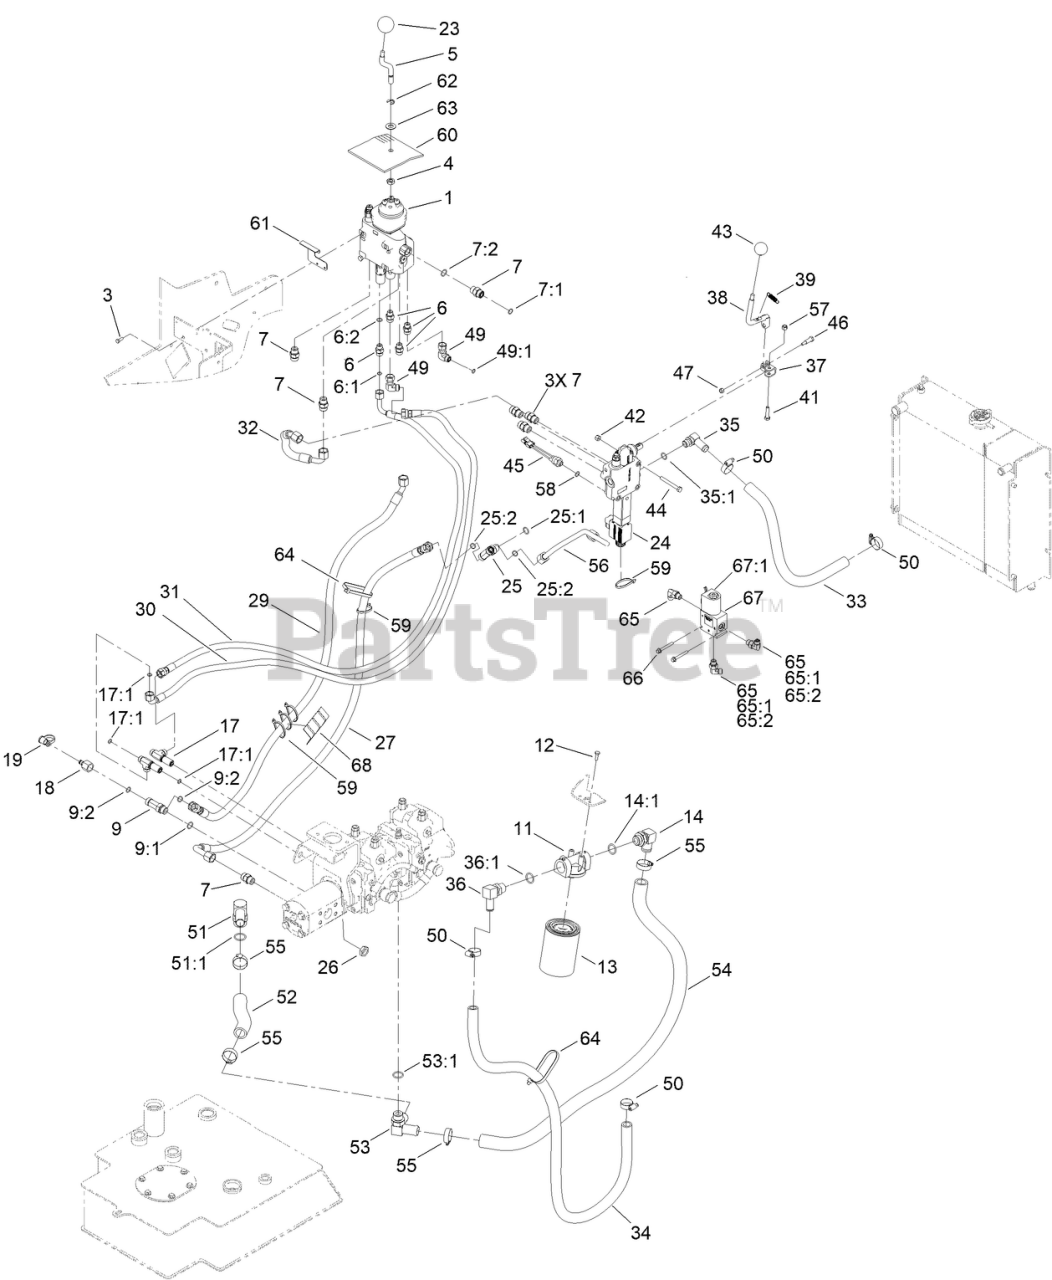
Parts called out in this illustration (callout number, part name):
1	VALVE-2 SPOOL
3	SCREW-HH
5	SHAFT-HANDLE, LIFT/TILT
6	FITTING-STRAIGHT
6:1	O-RING
6:2	O-RING
7	FITTING-STRAIGHT
7:1	O-RING
7:2	O-RING
9	FITTING-TEE
9:1	O-RING
9:2	O-RING
11	HEAD-FILTER
12	SCREW-HH
13	FILTER-OIL
14	FITTING-90
14:1	O-RING
17	FITTING-TEE, BULKHEAD
17:1	O-RING
18	FITTING
19	CAP-DUST
24	VALVE- AUX, DOUBLE DETENT
25	FITTING-HYD, TEE
25:1	O-RING
25:2	O-RING
26	NUT-LOCK
27	HYD HOSE ASM
29	HYD HOSE ASM
30	HYD HOSE ASM
31	HYD HOSE ASM
32	HYD HOSE ASM
33	HOSE-RETURN
34	HOSE-RETURN
35	FITTING-ELBOW, 90
35:1	O-RING
36	FITTING-ELBOW, 90
36:1	O-RING
37	BRACKET-AUXILARY
38	HANDLE ASM
39	SPRING-EXTENSION
41	SCREW-HH
42	NUT-LOCK, NI
44	SCREW-HH
45	SWITCH-BALL
46	BOLT-SHOULDER
47	NUT-LOCK, NI
49	FITTING-HYD, 90 DEG
49:1	O-RING
50	CLAMP-HOSE
51	FITTING-HYD, 90 DEG
51:1	O-RING
52	HOSE-SUCTION
53	CONNECTOR
53:1	O-RING
54	HOSE-RETURN
55	CLAMP-HOSE
56	HYDRAULIC TUBE ASM
57	NUT-LOCK, NI
58	O-RING
59	TIE-CABLE
60	DEFLECTOR-AIR
61	BRACKET-DEFLECTOR
62	RING-RETAINING
63	WASHER-PIVOT
64	TIE-CABLE
65	FITTING-ELBOW, 90 DEG
65:1	O-RING
65:2	O-RING
66	SCREW-HHF
67	SOLENOID VALVE
67:1	SOLENOID COIL
68	PROTECTOR-HOSE
